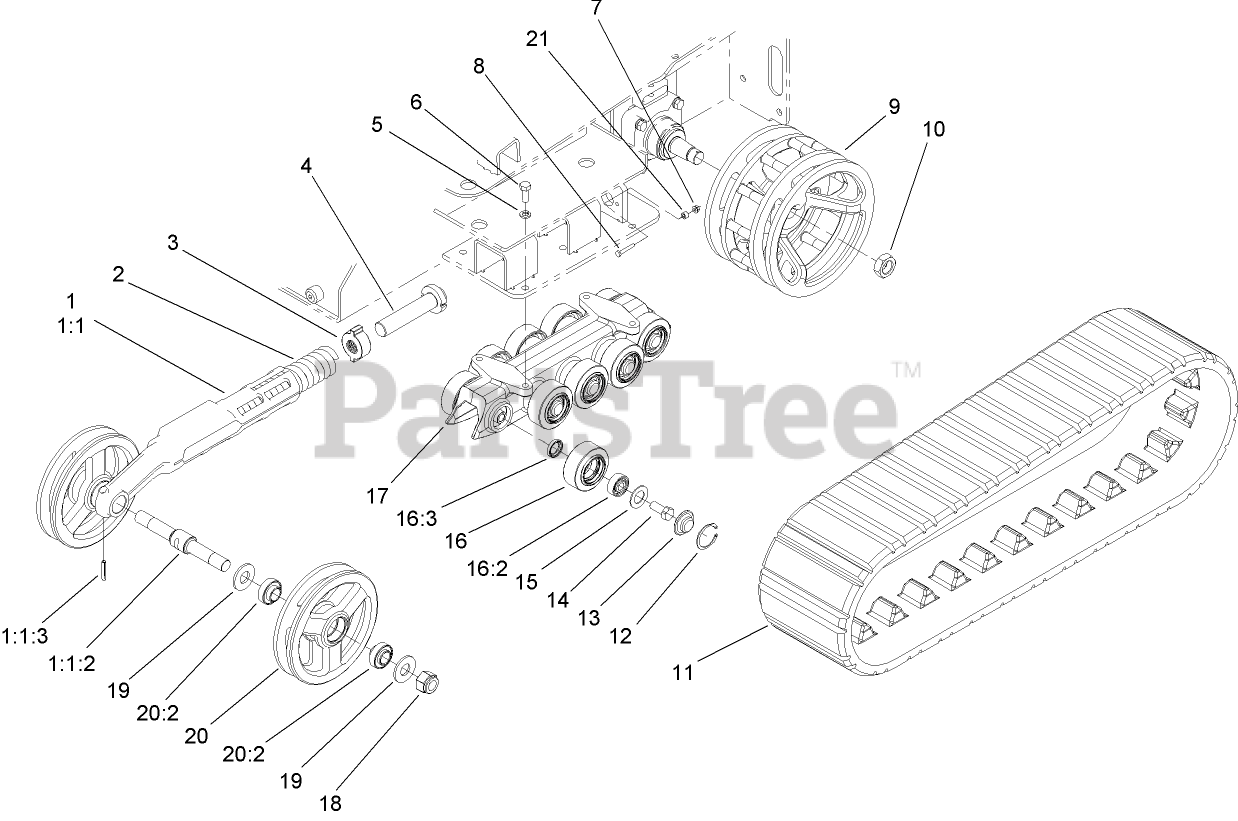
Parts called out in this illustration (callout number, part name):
1	TENSIONER ARM ASM
1:1	ARM-TENSIONER
1:1:2	SHAFT-TENSIONER
1:1:3	PIN-GROOVE
2	SPRING-COMPRESSION
3	BLOCK-TENSIONER
4	BOLT-TENSIONER
5	WASHER-LOCK
6	SCREW-HH
7	NUT-HHF
8	SCREW-HH
9	WHEEL-DRIVE
10	NUT-HEX
11	TRACK
12	RING-SNAP, INTERNAL
13	CAP-WHEEL, BEARING
14	SCREW-HH
15	Gasket-Bogie
16	Road Wheel ASM
16:2	BEARING
16:3	SEAL-OIL
17	GUIDE-TRACK
18	NUT-HEX, NI
19	WASHER-PLAIN
20	Tensioner Wheel ASM
20:2	Bearing-Ball
21	SPACER
